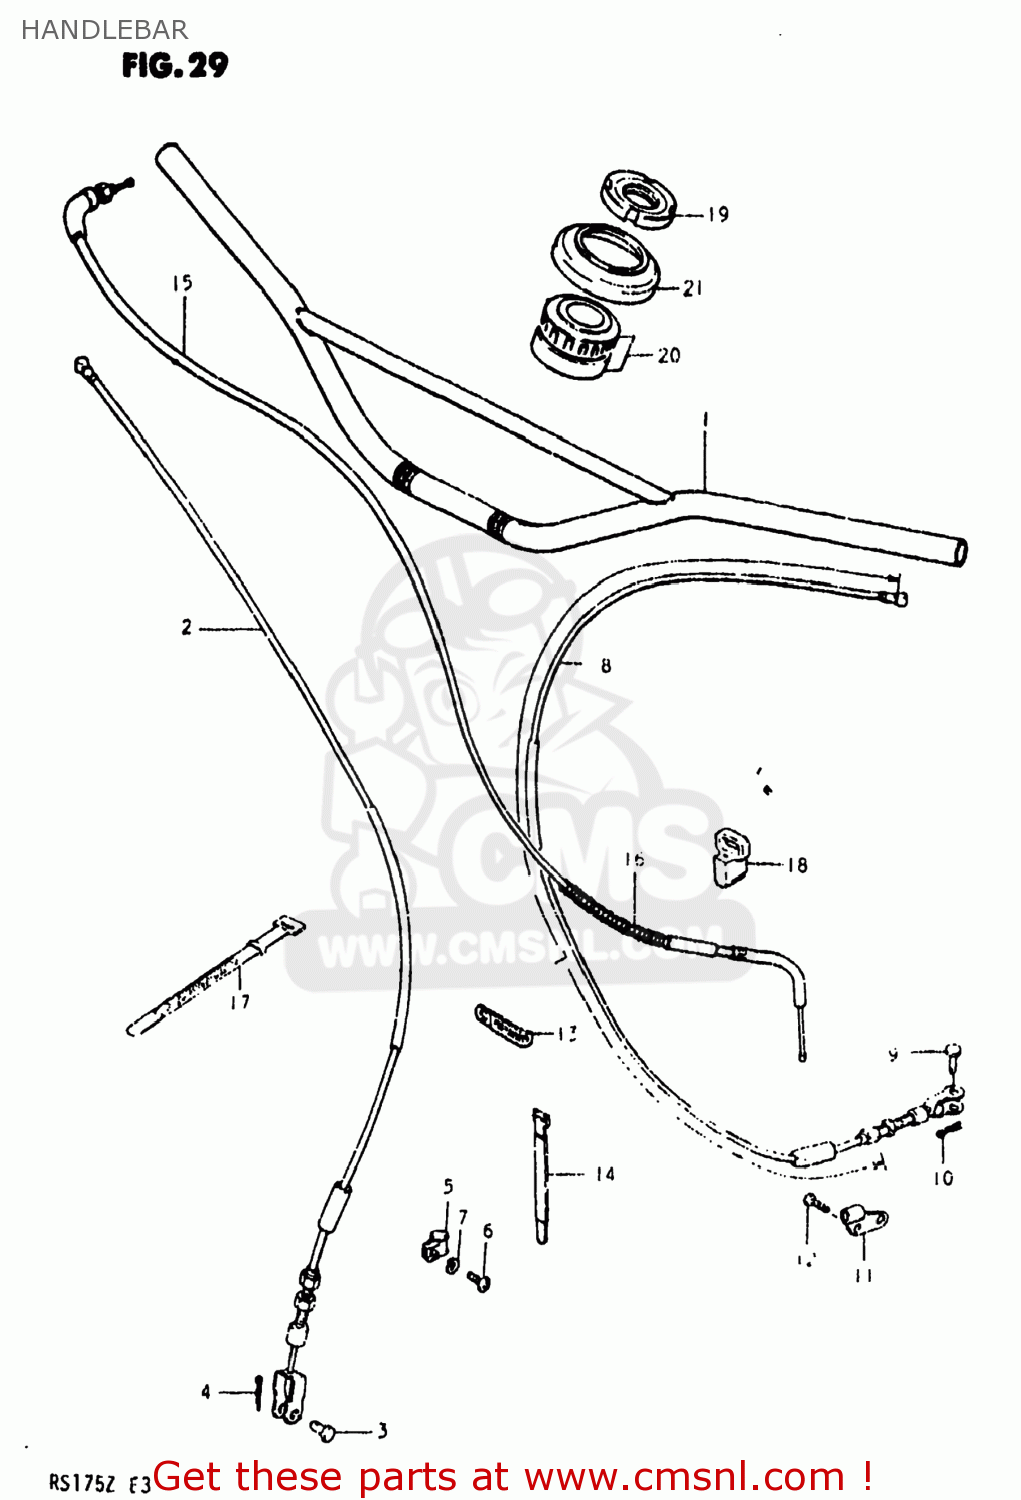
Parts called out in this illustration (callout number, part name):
1	HANDLEBAR
2	CABLE ASSEMBLY,FRONT BRAKE
3	PIN(L:17.5)
4	PIN
5	GUIDE,CABLE
6	SCREW
7	LOCK WASHER
8	CABLE ASSY,CLUTCH
9	PIN(L:13)
10	PIN
11	STOPPER,CLUTCH CABLE
12	SCREW
13	CLAMP L:35
14	CLAMP
15	CABLE ASSEMBLY,THROTTLE
16	PROTECTOR,CABLE
17	CLAMP(L:120)
18	GUIDE,CLUTCH CABLE
19	NUT,STEERING STEM(25X44X10)
20	TAPER,ROLLER BEARING
21	DUST SEAL,STEERING,UPPER
